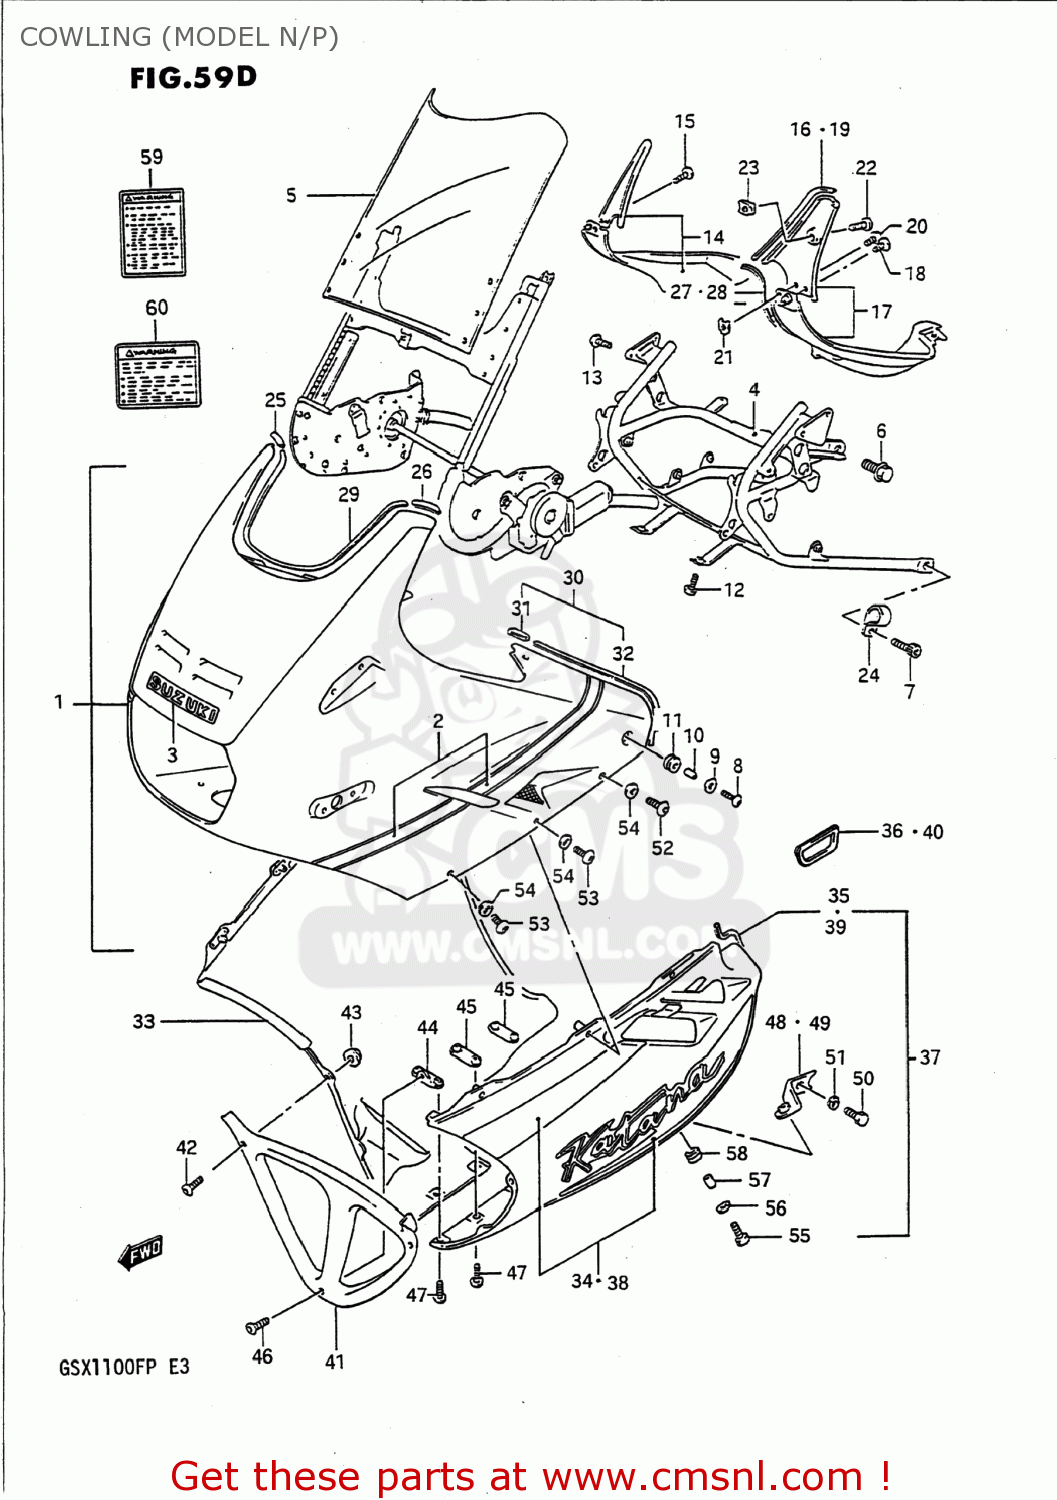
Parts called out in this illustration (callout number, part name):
1	BODY ASSEMBLY,COWLING
2	TAPE,COWLING,UPPER,LEFT
3	EMBLEM,RR COMBN LAMP
4	BRACE,COWLING
5	WINDSCREEN
6	BOLT(10X12)
7	BOLT
8	SCREW(6X20)
9	WASHER(6.5X18X1)
10	SPACER
11	CUSHION
12	SCREW(6X16)
13	SCREW 6X12
14	PANEL ASSY,R
15	SCREW
16	MOLDING,COWL.
17	PANEL ASSY,L
18	SCREW
19	MOLDING,COWL.
20	SCREW, FRONT & REAR
21	NUT
22	SCREW
23	NUT
24	CLAMP
25	CAP,PANEL & COWLING,R
26	CAP,PANEL & COWLING,L
27	MOLDING,COWLING PANEL,R
28	MOLDING,COWLING PANEL
29	MOULDING
30	MOLDING,COWLING BODY SIDE
31	COVER,MOLDING END
32	MOLDING,COWLING BODY SIDE
33	COVER ASSEMBLY,COWLING,LOWER
34	TAPE SET,COWLING,LOWER
35	MOLDING,COWLING,LOWER
36	MOLDING,INLET
37	COVER ASSEMBLY,COWLING,LOWER
38	TAPE SET,COWLING,LOWER
39	MOLDING,COWLING,LOWER
40	MOLDING,INLET
41	COVER,COWLING,LOWER,FRONT
42	SCREW(5X14)
43	NUT
44	BRACE,COWLING LWR COVER
45	BRACE,COWLING LWR COVER RR
46	SCREW(6X12)
47	SCREW(6X16)
48	BRACE,COWLING LWR,R
49	BRACE,COWLING LWR,L
50	BOLT 8X12
51	LOCK WASHER
52	SCREW(6X20)
53	SCREW(6X16)
54	WASHER
55	SCREW(6X20)
56	WASHER(6.5X18X1)
57	SPACER(6.4X9.2X12)
58	CUSHION
59	LABEL (WARNING SCREEN)
60	LABEL
61	LABEL (TIRE AIR PRESSURE)
